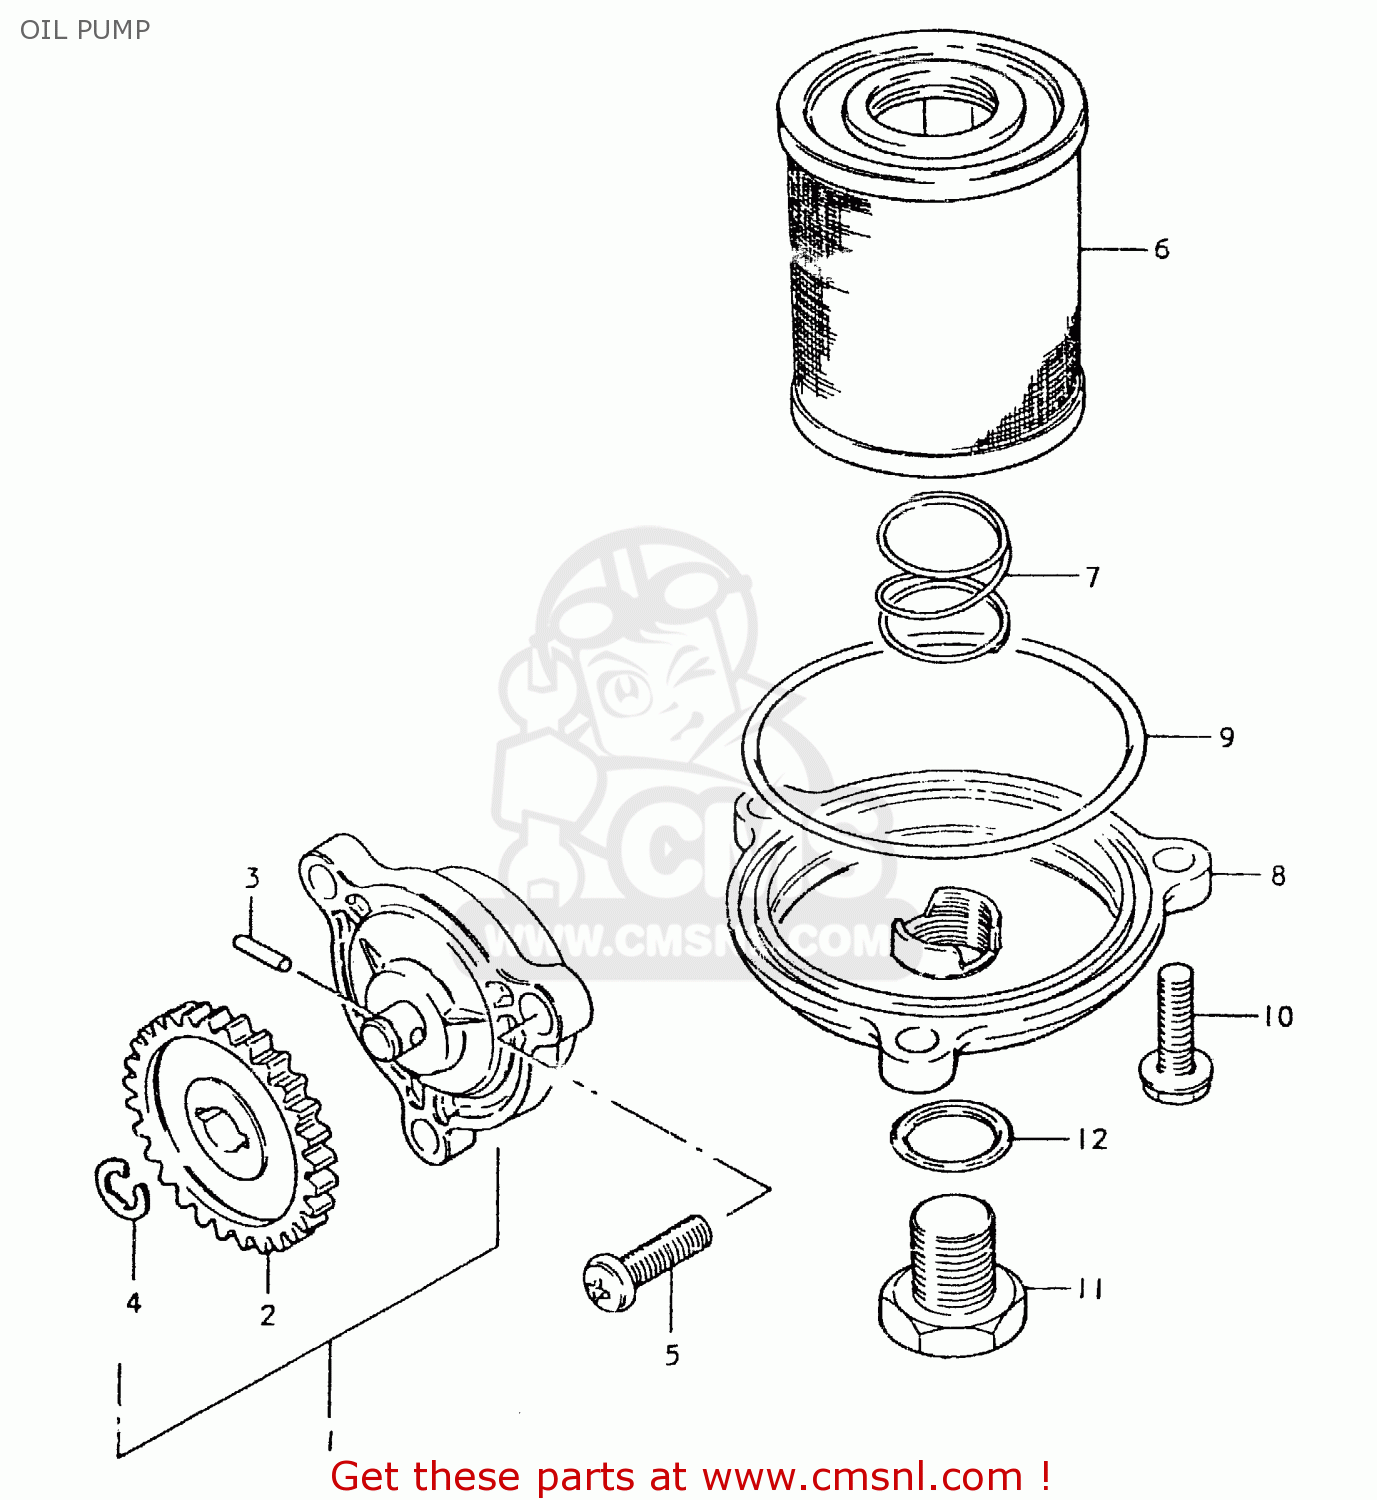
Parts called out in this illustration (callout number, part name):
1	PUMP ASSEMBLY,ENGINE OIL
2	GEAR,OIL PUMP DRIVEN
3	PIN(2.5X11.8)
4	E RING 6MM
5	SCREW
6	STRAINER,OIL
7	SPRING
8	CAP,ENGINE OIL STRAINER
9	O RING(D:2.4,ID:62.6)
10	BOLT,REAR
11	PLUG
12	GASKET(14X19.2X2) (NAS)
